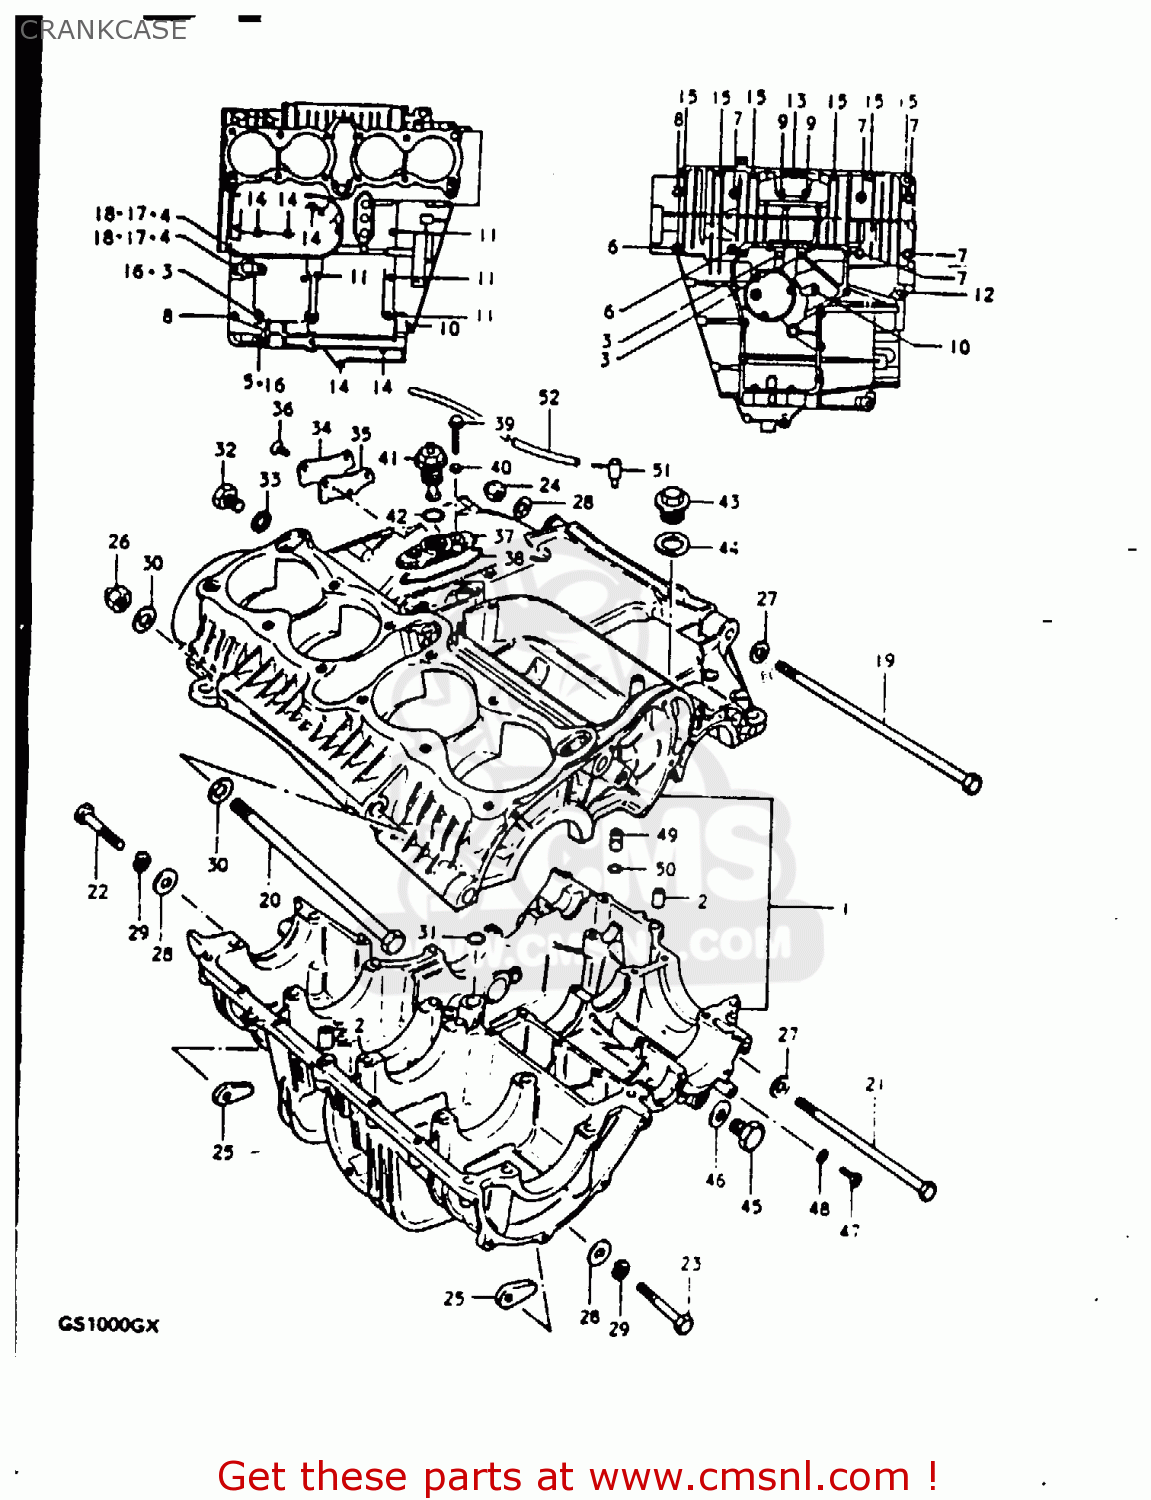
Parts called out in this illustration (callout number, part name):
1	CRANKCASE SET
2	PIN
3	BOLT
4	BOLT
5	BOLT
6	BOLT
7	BOLT 8X90
8	BOLT 8X65
9	BOLT
10	BOLT (6X90)
11	BOLT (6X75)
12	BOLT
13	BOLT ,6X50
14	BOLT,UNDER
15	BOLT 6X35
16	NUT
17	NUT
18	GASKET 8.2X14X1 (NAS)
19	BOLT 10X270
20	SHAFT,REAR SWING ARM
21	BOLT(10X165)
22	BOLT 10X60
23	BOLT (10X50)
24	NUT
25	NUT
26	NUT 12MM
27	WASHER(10.5X20X3.2)
28	WASHER
29	LOCK WASHER
30	WASHER
31	O RING(D:3.2,ID:12.9)
32	PLUG (14X12)
33	GASKET(14X19.2X2) (NAS)
34	CAP,OIL GALLERY
35	GASKET,OIL GALLERY (MCA)
36	SCREW
37	HOUSING,OIL PRESSURE SWITCH
38	O RING,PRESSURE SWITCH HOUSING
39	BOLT
40	GASKET (NAS)
41	SWITCH ASSEMBLY
42	O RING(D:1.9,ID:18.8)
43	PLUG
44	GASKET
45	PLUG
46	GASKET(14X19.2X2) (NAS)
47	SCREW(6X10)
48	GASKET (NAS)
49	UNION
50	O RING(D:1.05,ID:3.1)
51	BPLUG,BEVEL GEAR BREATHER
52	HOSE
